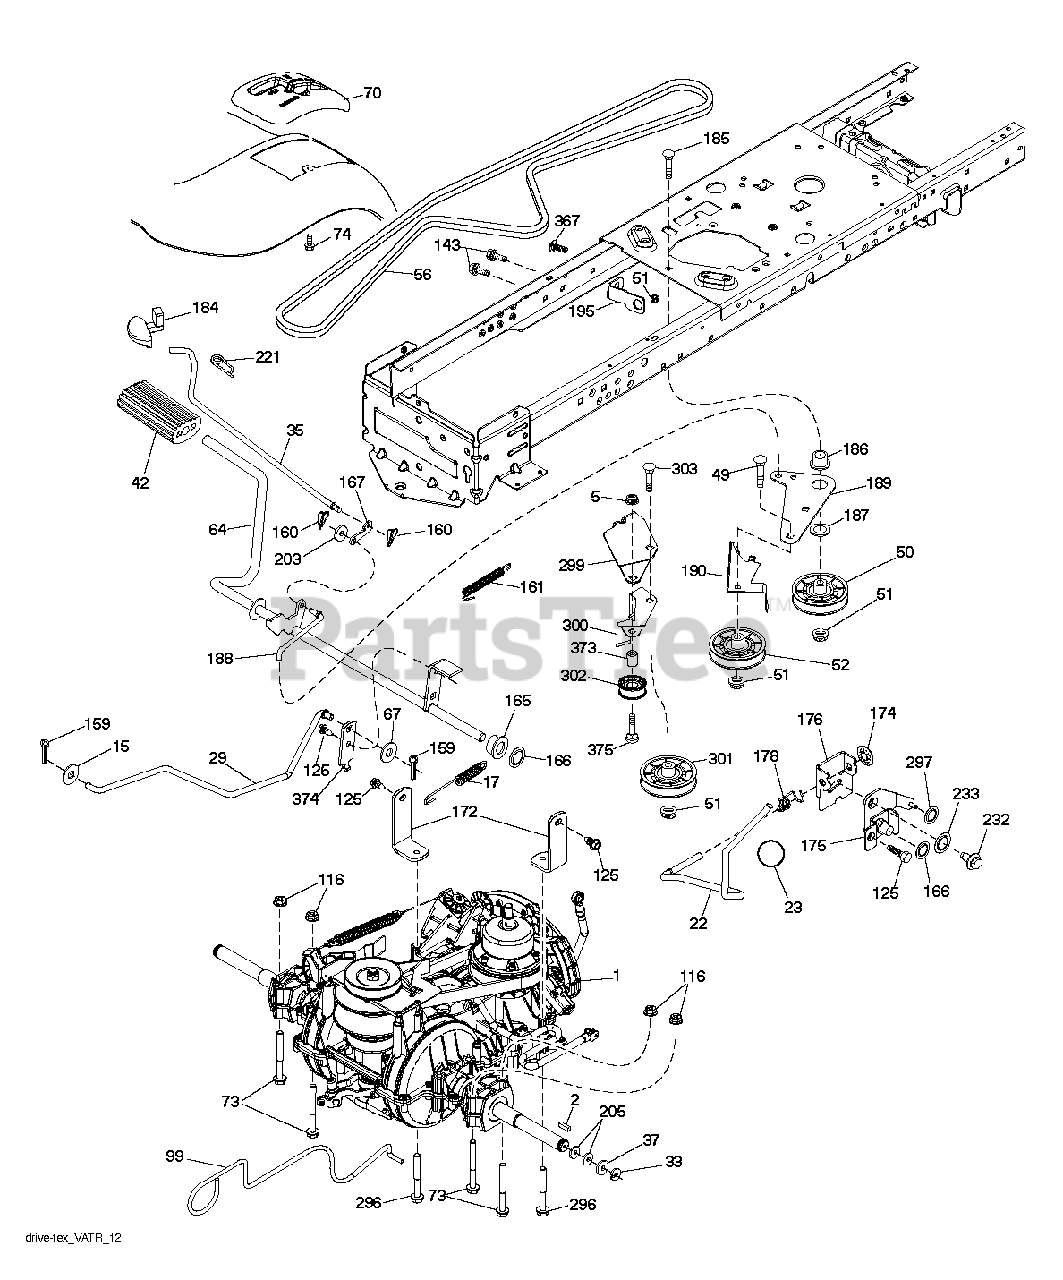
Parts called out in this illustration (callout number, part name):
2	SQUARE KEY
15	WASHER
17	SPRING.BRAKE.K46.GREEN
22	ROD.SHIFT.LT.TEX.VARIATOR
23	KNOB.DELUXE.(PISTOL.GRIP).BLAC
29	RB ROD.BRAKE.VARIATOR.SD2
35	ROD.BRAKE.PARTK.HUSQ.TEX
37	WASHER.HARDENED
42	PEDAL COVER T
50	IDLER.FLAT.910.OFFSET
51	NUT LOCK FLG 3/8-16 UNC
52	IDLER.V-GROOVE.910.OFFSET
56	BELT.DRIVE.MOWER.TEX.42"
64	SHAFT.ASM.PEDAL.BRAKE.
67	WASHER
73	BOLT HEX 5/16-18 GR 5
74	SCREW.HI-LO.CONSOLE
99	ROD.BYPASS.VARIATOR.GEN2
116	NUT LOCK HEX FLANGE 5/16-18
125	SCREW
143	SCREW LT
159	COTTER PIN
160	RETAINER CLIP
161	SPRING, RETURN LT
165	BUSHING.SHAFT.BRAKE.HAND
166	NUT.PUSH.625
167	LATCH.BRAKE.SPRING
172	STRAP.TORQUE.VARIATOR
174	NUT.PUSH.500.2006
175	SHAFT.ASM.SHIFT.VARIATOR
176	ARM.CLEVIS.ROD.SHIFT
178	SPRING.SHIFT.GT2006
184	RB HANDLE.PARKG.BRK.HUS/PRED
186	SPACER.RETAINER
187	WASHER 12/32X2X10GA
188	RP LINK.CLUTCH.GROUND.DRIVE
189	BELLCRANK.GROUND.DRIVE.TEX.
190	KEEPER.BELLCRANK.DRIVE
195	BRACKET.BRAKE.BRAKE.VAR.SD
203	WASHER
221	RETAINER.SPRING.CLIP.H
232	BOLT FIN HEX 7/16-14 X 1
233	WASHER SERRATED
296	SCREW.THDROL.5/16-18
297	NUT.PUSH.1/4
299	BRACKET.MOUNT.IDLERS
300	KEEPER.IDLERS.REAR.VARIATOR
301	PULLEY.IDLER.V-GROOVE
302	RB PULLEY.IDLER.FLAT.2.0"OD RP
303	BOLT CARRIAGE
367	BOLT D
373	SPACER.IDLER
374	ARM.CONTROL.BRAKE
